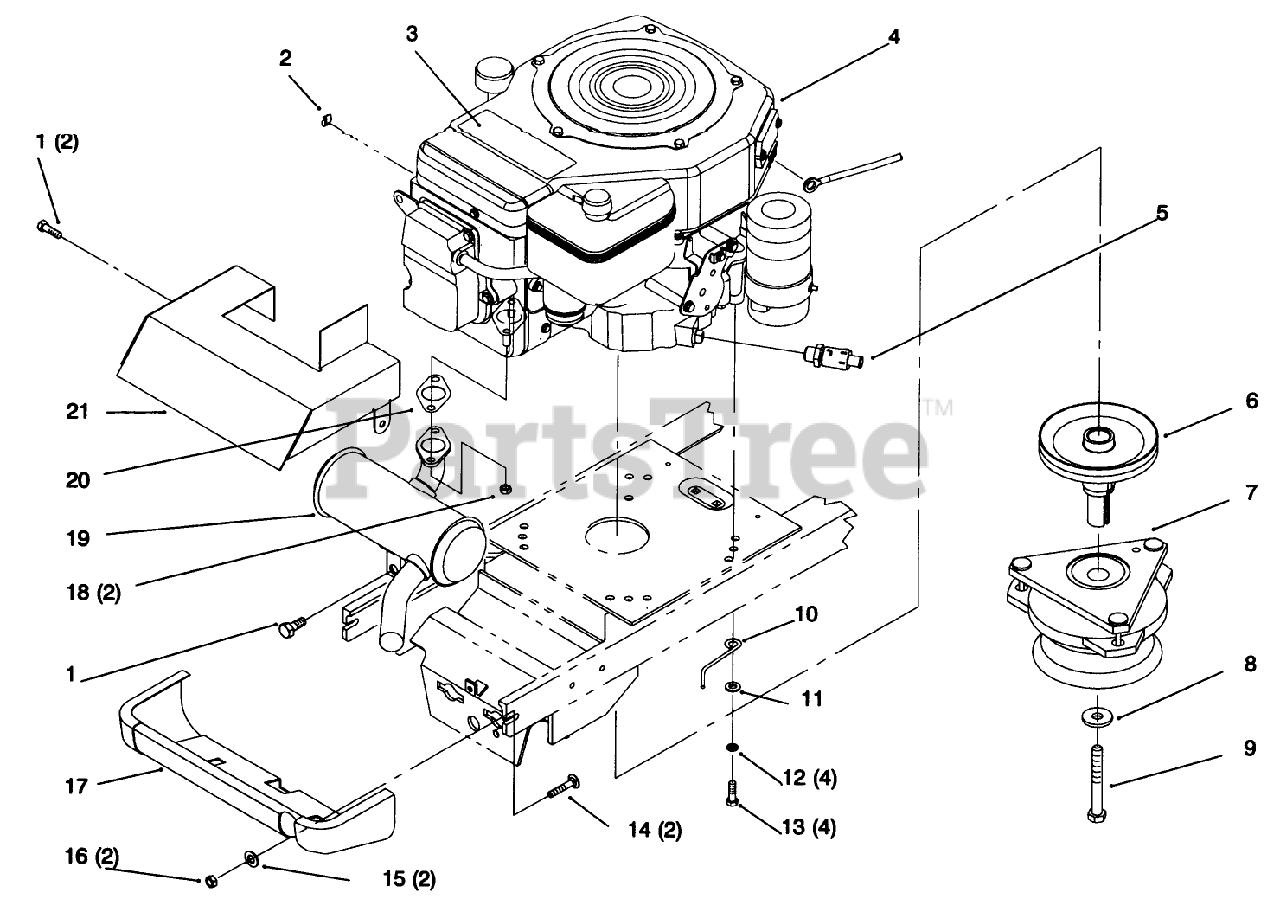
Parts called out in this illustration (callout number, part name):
1	SCREW
2	CLIP-RETAINER, WIRE
4	Engine-Kohler (Only On: 72046)
4	Engine-Kohler (Only On: 72064)
5	VALVE-DRAIN, OIL
6	PULLEY-ENGINE
7	CLUTCH - ELEC PTO
7	CLUTCH - PTO
8	WASHER
9	HHCS-M10X1.5X110 ESL
12	WASHER-LOCK
14	BOLT-CARR
15	WASHER-FLAT
16	NUT-LOCK, NI
20	KOHLER 12-041-03
21	SHIELD-MUFFLER
